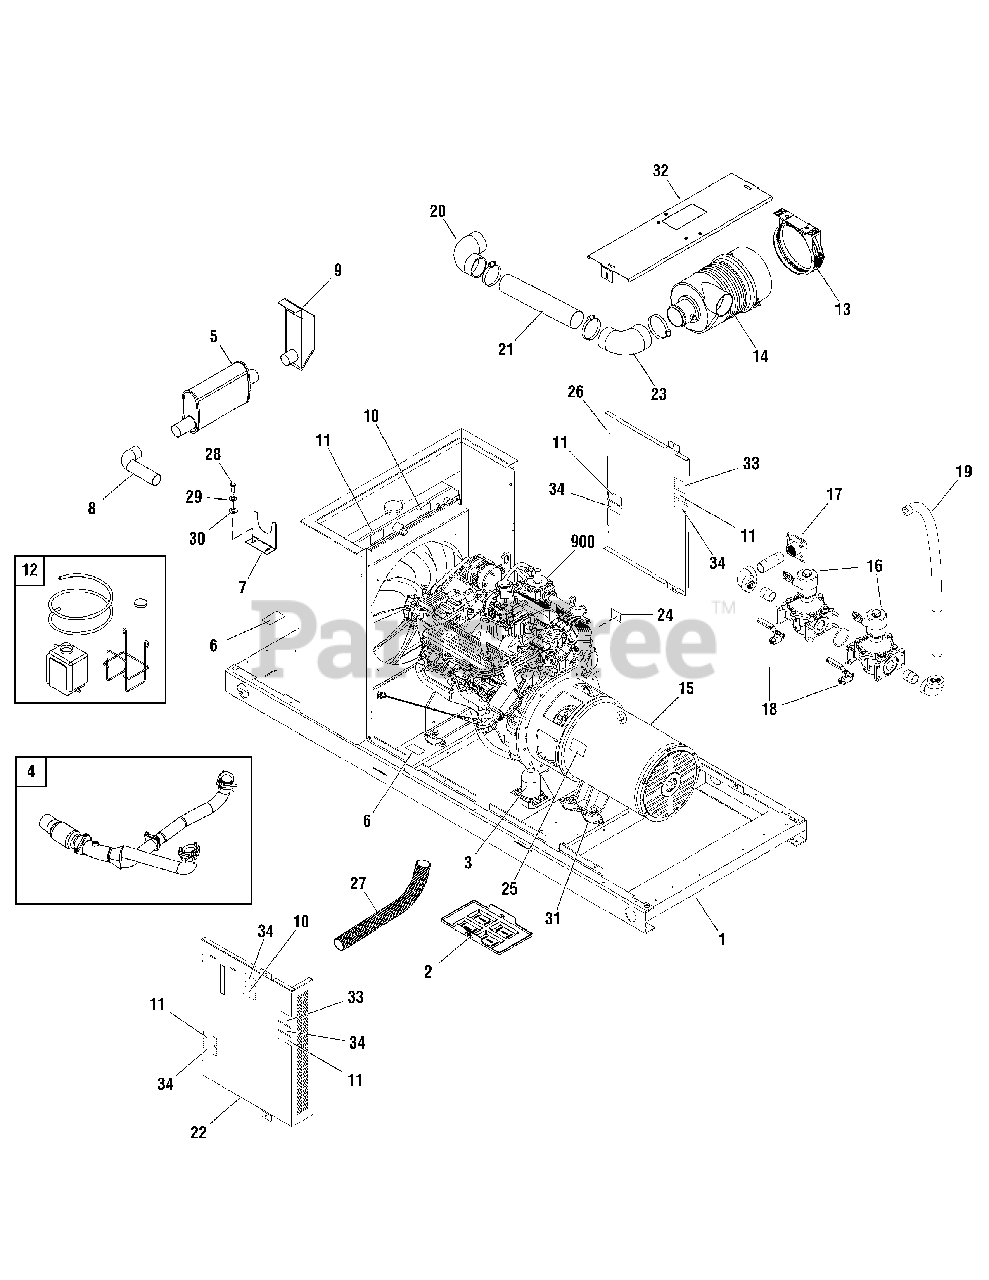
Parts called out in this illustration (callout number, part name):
4	KIT, Exhaust
5	MUFFLER
6	DECAL
7	BRACKET, Muffler
9	DIFFUSER
11	DECAL
12	BOTTLE, Overflow
24	DECAL
28	* CAPSCREW, Hex Head, 1/4-20 x 3/4
29	* WASHER, Lock, 1/4-M6
30	* WASHER, Flat, 1/4
31	MOUNT, Vibration
33	DECAL
34	DECAL
900	** ENGINE
